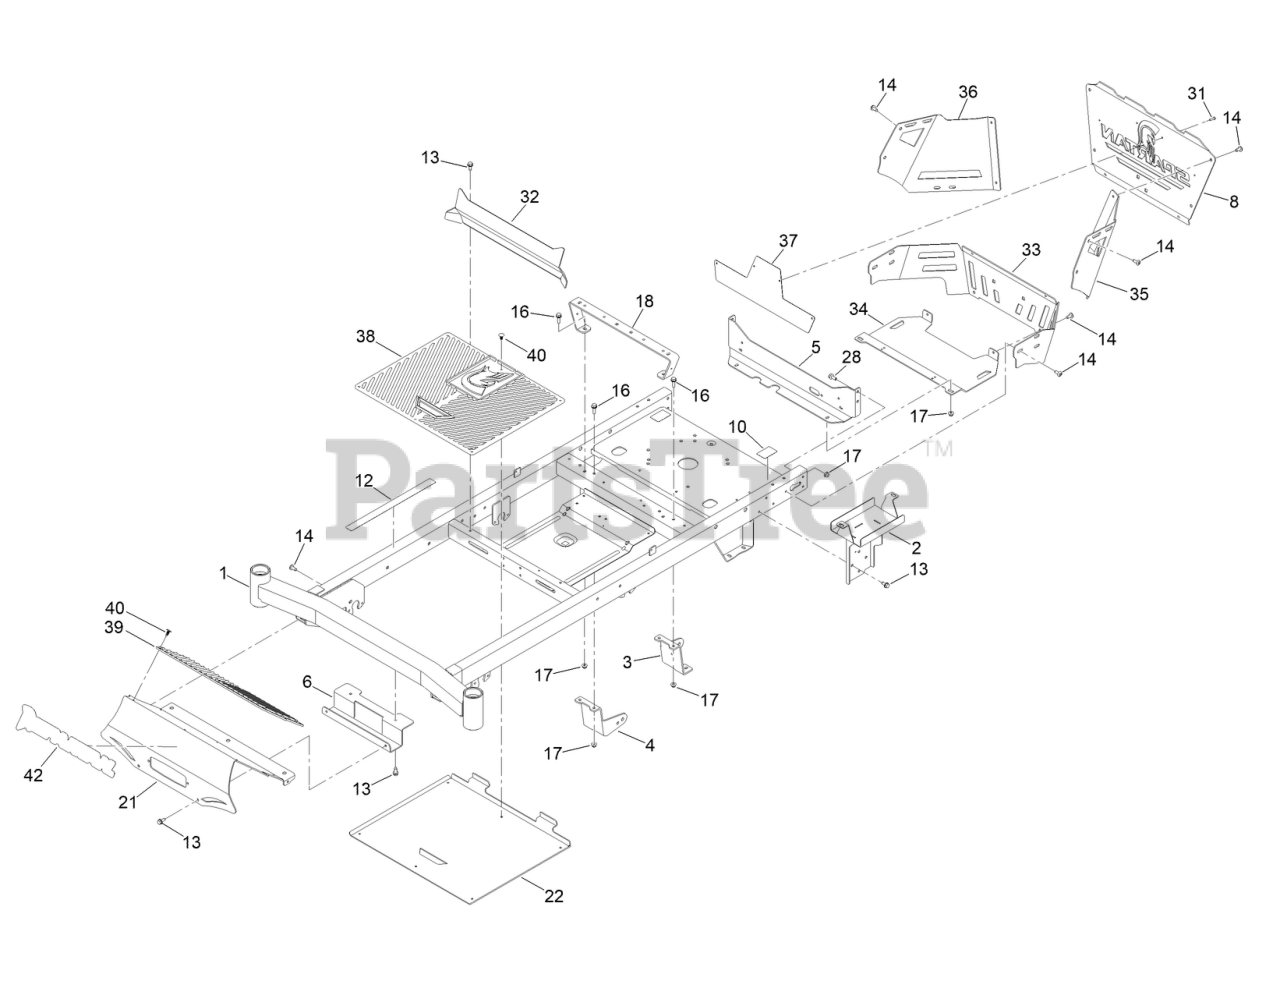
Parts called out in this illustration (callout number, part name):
1	FRAME ASM
2	WA-BATTERY MOUNT
3	MOUNT-DRIVE, LH
4	MOUNT-DRIVE, RH
5	PLATE-MOUNT
6	BRACKET-SUPPORT
8	SHIELD GUARD ENGINE
10	DECAL-BYPASS
12	DECAL-WARNING
13	SCREW-HWHTF
16	SCREW-HHF
17	NUT-HF
18	SUPPORT-SEAT
21	PLATE-FRONT
22	PLATE-FLOOR
28	SCREW-HHF
31	RIVET-TRIFOLD
32	PLATE-KICK
33	GUARD MUFFLER
34	GUARD MUFFLER
35	COWLING-REAR, LH
36	COWLING-REAR, RH
37	PLATE-REAR
38	FLOOR MAT
39	FRONT FOOT MAT (SPARTAN)
40	PLUG-PLASTIC
42	DECAL-SPARTAN, FRONT
